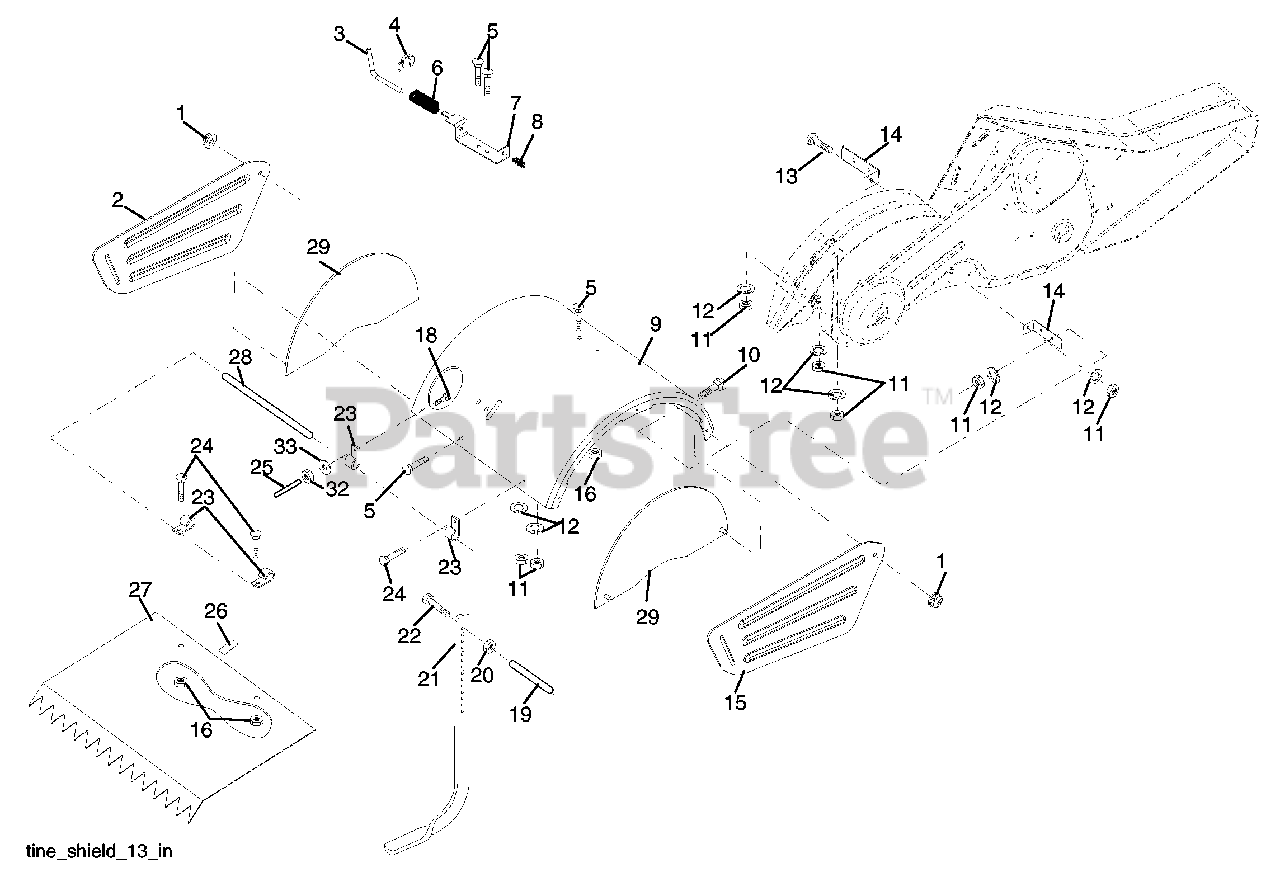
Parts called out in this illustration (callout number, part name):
1	Nut, Lock Hex Flange 5/16-18
2	Shield, Side, Outer L. H.
3	Pin, Stake, Depth
4	Ring, Klip
5	Bolt, Rdhd Sqnk 5/16-18 x 3/4
7	Bracket, Latch
8	Spring, Depth Stake
9	Shield, Tine
10	Bolt, Carriage 5/16-18 UNC x 1
11	Nut, Hex 5/16-18
12	Washer, Lock 5/16
13	Bolt, Carriage 5/16-18 x 1-1/4
14	Bracket, Shield Tine
15	Shield, Side, Outer R.H.
16	Nut, Hex Flange 1/4-20 UNC
18	Bolt, Carriage 1/4-20 x 1-1/4 Gr.
20	Nut, Hex 3/8-16
21	Stake, Depth
22	Bolt, Hex 3/8-16 x 2
24	Bolt, Carriage 1/4-20 x 1/2 Gr. 5
25	Cap, Vinyl
26	Pad, Idler
27	Shield, Leveling
28	Pin, Hinge
29	Shield, Side
30	Locknut, Flange 5/16-18
32	Nut Fin Hex 1/4-20 UNC
33	Washer Lock Hvy Helical 1/4
